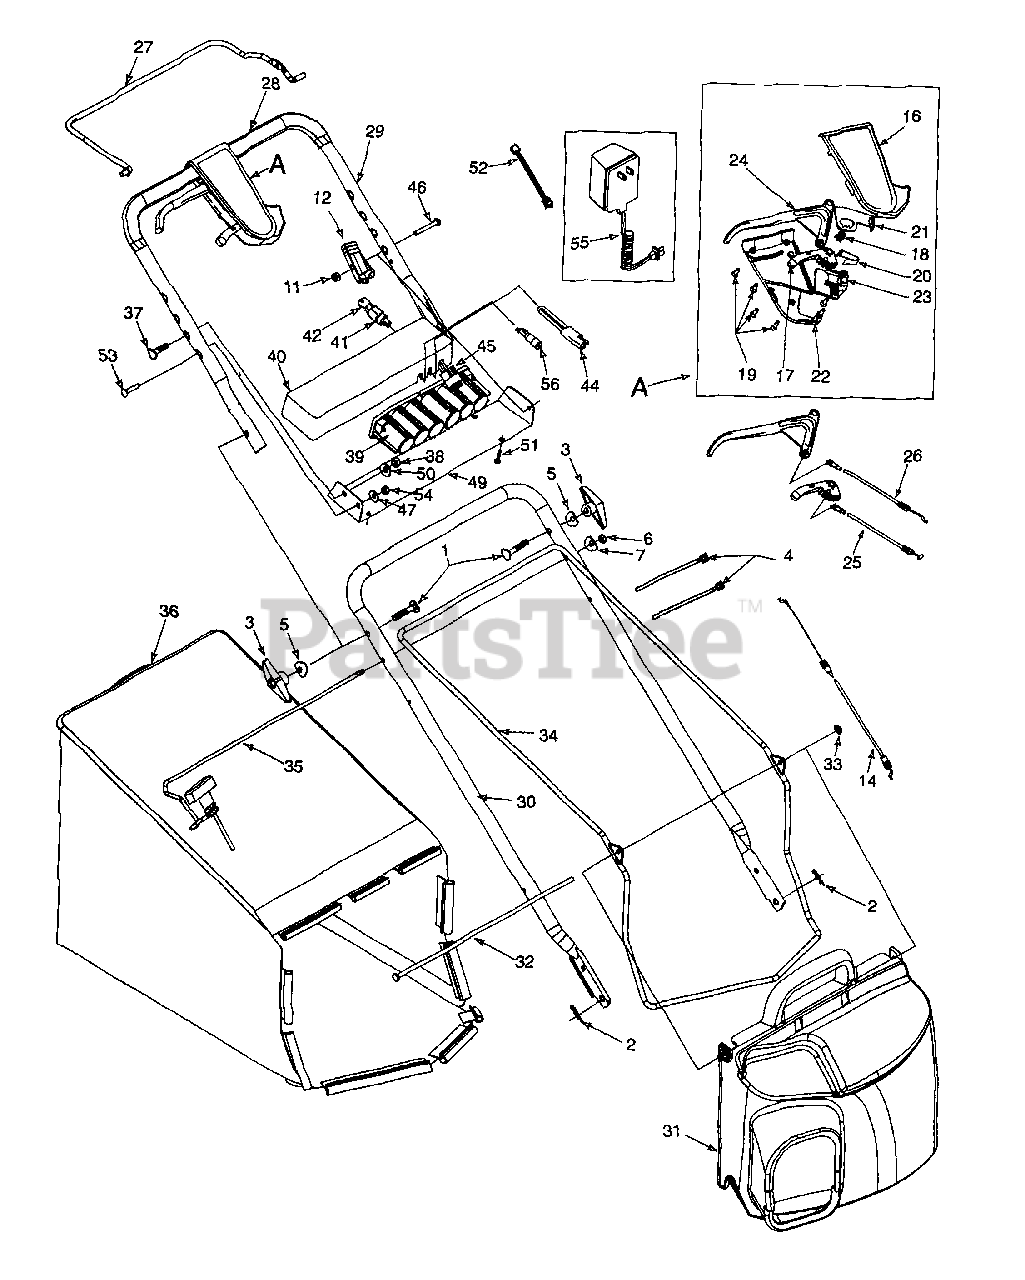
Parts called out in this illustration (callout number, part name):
1	Bolt Cur. Carr. 5/16-18 x 2.0
2	Cotter Pin .072 x 1.12 Lg.
3	Knob Assembly 5/16-18
4	Strap 4.3" Lg.
5	Wash. Sad. .320 ID x .830 OD
6	Handle Knob 1/4-20
7	Saddle Washer
11	Nut 1/4-20 Top Lock Nut Insert
12	Control Cable Housing
14	Control Cable 44" Lg.
16	Upper Control Housing
17	6-Speed Shift Lever
18	Gear Insert
19	C Sunk Tap Screw #10-16 x .625
20	Shift Lever Spring
21	6 Spd. Rack Cable Brkt.
22	Lower Control Housing
23	Cable Mounting Cap
24	Control Lever
25	6 Spd. Cable
26	Self Prop. Cable, 52"
28	Foam Grip (2 Req'd.)
31	Grassbag Cover w/logo
32	Pivot Rod
33	Cap Nut
36	Grassbag
37	Cur. Carr. Bolt 5/16-18 x 1" Lg.
38	Hex Nut 5/16-18 Thd.
39	Battery Pack - 12 Volt
40	Battery Tray
41	Ignition Switch
42	Ignition Key
44	Plug
45	Wire Harness
46	Hex Bolt 1/4-20 x 1.3" Lg.
47	Bell Wash 1/4" I.D.
51	Truss Mch. Tap Scr. 1"
52	Harness Ext.
53	Scr. 1/4-20 x 1.25
54	Hex Nut 1/4-20
55	Battery Charger
56	Fuse Holder
